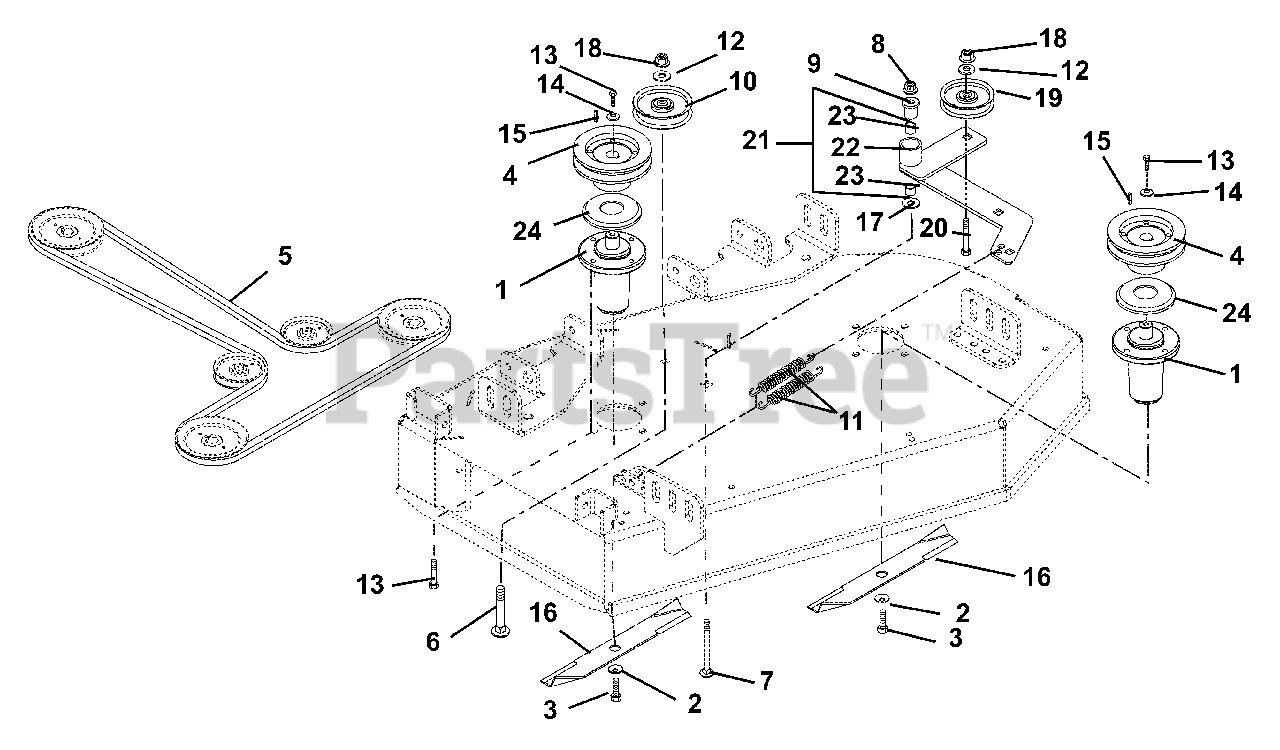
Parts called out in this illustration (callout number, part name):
1	ASM,MAINT FREE SPINDLE
2	WSHR-BLVL .669X1.535X.138
3	BLT-HEX .62-18X1.75 GR8 YWZC
4	SHEAVE, 5.00 SPINDLE (1.000ID)
5	V-BELT, HB-WRAPPED
6	@BLT-RDHDSQNK .38-16X2.75 G5YZ
7	@BLT-RHDSSQNK .50-13X3.50 G5YZ
8	@NUT-LK-TOP-FLG .50-13 YWZC
9	BEARING, PEDESTAL
10	IDLER-FLAT 4.00X.38 (2.00 W)
11	SPRING, EXT0NSION DIA1.0X6.0LG
12	WSHR-FL-STL .375X1.125X.065YWZ
13	BLT-HEX .38-16X1.00 YZ GR8
14	WSHR,FLT STL.406X1.50X.245YWZC
15	KEY, SQ .25X.25X1.00 RC 40-50
16	BLADE, 50" MOWER SAND
16	BLD,MULCHING 50" MWR
17	@WSHR-FL-STL.563X1.38X.109YWZC
18	@NUT-LK-TOP-FLG .38-16 YWZC
19	IDLER, FLAT 4.00 X .38 (1.OOW)
20	@BLT-RDHDSQNK .38-16X2.00 G5YZ
21	ASSM, IDLER ARM PIVOT
22	WMT, IDLER PIVOT ARM
23	BRG, 1.00 X 1.12 X .75
24	SLINGER, DUST
